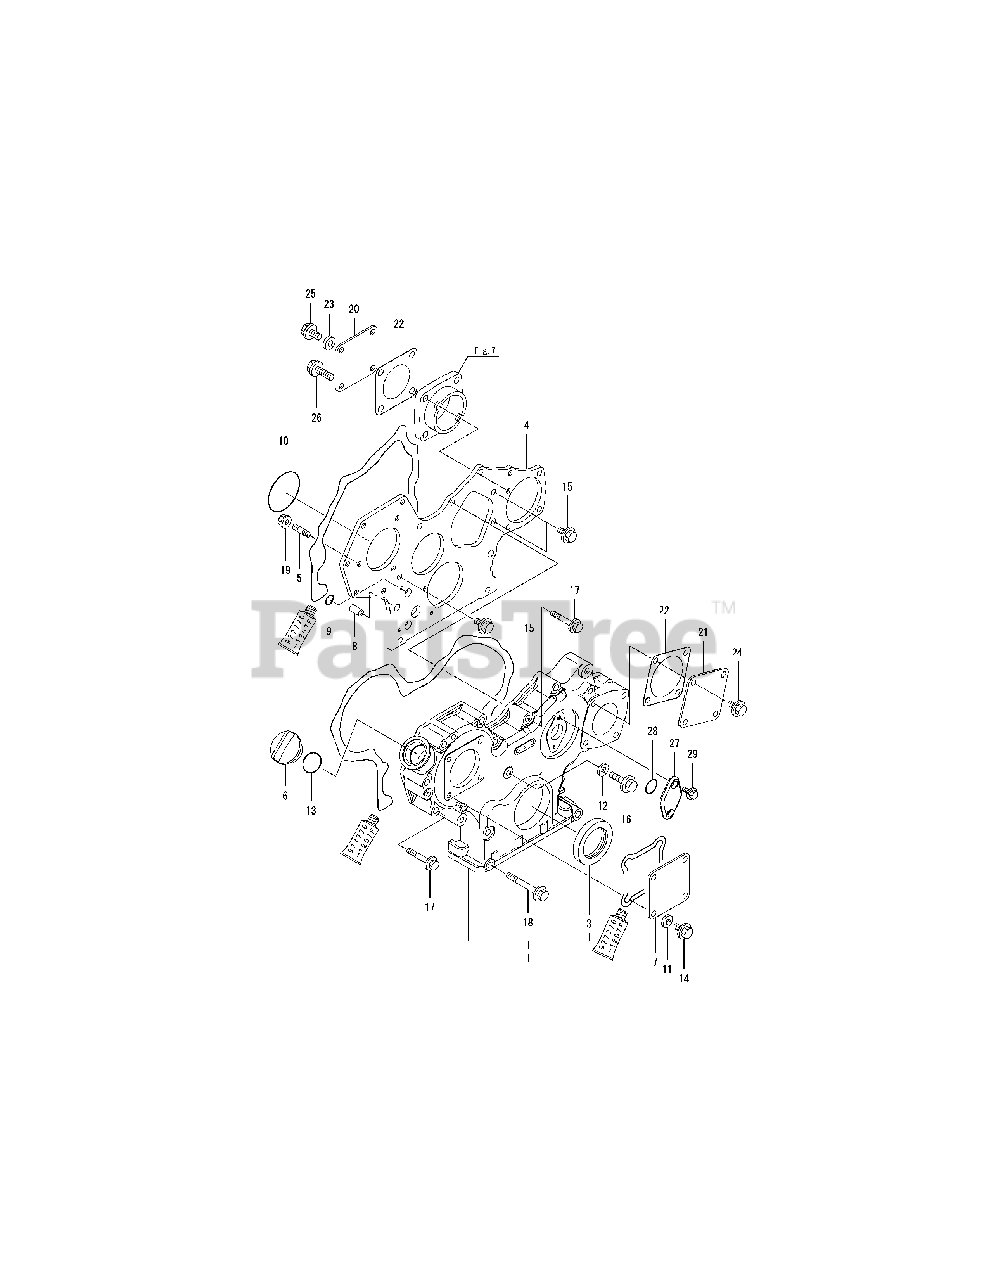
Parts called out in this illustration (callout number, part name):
1	HOUSING ASSY, GEAR
4	FLANGE, GEAR CASE
10	O-RING, F.I.PUMP
11	SEAL WASHER 8S
12	SEAL WASHER 8S
13	O-RING 1A P-32.0
14	BOLT M 8X 16 PLATED
15	BOLT M 8X 16 PLATED
16	BOLT M 8X 30 PLATED
17	BOLT M 8X 55 PLATED
18	BOLT M 8X 85 PLATED
23	SEAL WASHER 8S
24	BOLT M 8X 16 PLATED
25	BOLT M 8X 20 PLATED
26	BOLT M 8X 30 PLATED
27	COVER, TACHOMETER
28	O-RING 1A S-24.0
29	BOLT M 6X 16 PLATED
